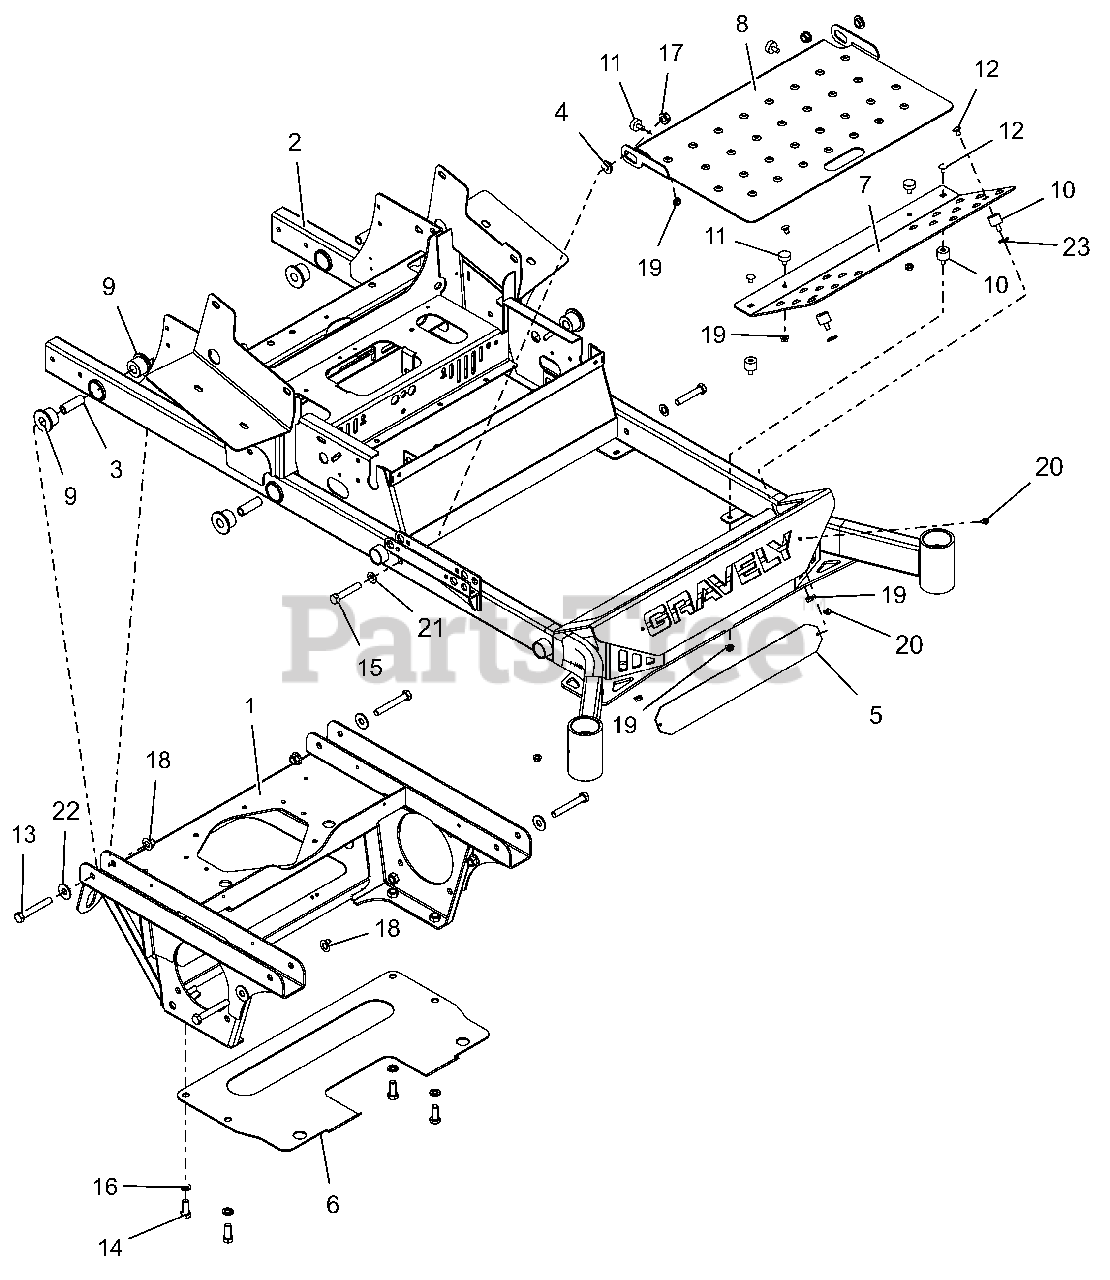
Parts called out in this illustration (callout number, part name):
1	PT200/400 AXLE/ENG FRM WMT-RED
2	52-60"PT200/400 FRAME W/DECALS
3	BSHG-SLV .50X.75X2.23
4	BSHG-FLG .515X.750X.310X1.120
5	BUMPER LOGO BACKING PLATE -BLK
6	PLATE-TRANSMISSION SKID
7	FOOTREST W/ SAFTEY DECALS
8	INSPECTION PANEL W/SAFE DECAL
9	BSHG-FLG .75X1.51X1.13X2.0 URE
10	BUMPER,STUD MNTD W/FEMALE INSR
11	BUMPER, RUBBER
12	@BLT-RDHDSQNK .31-18X.50 G5YZ
13	@BLT-HEX .50-13X3.50 GR5 YWZC
14	@BLT-HEX .50-13X1.25 GR5 YWZC
15	@BLT-HEX .50-13X2.75 GR5 YWZC
16	@WSHR-LK .50X.125 REG YWZC
17	NUT-LK-CTR-FLG .50-13 YWZC
18	@NUT-LK-NYL-FLG .50-13 YWZC
19	@NUT-SPNLK-FLG .312-18 YWZC
20	SCR-TAP .25-20X.50 HWH TR YWZ
21	WSHR-FL-STL.531X1.00X.063 YWZC
22	@WSHR-FL-STL.563X1.38X.109YWZC
23	@WSHR-FL-STL.38X.875X.083 YWZC
